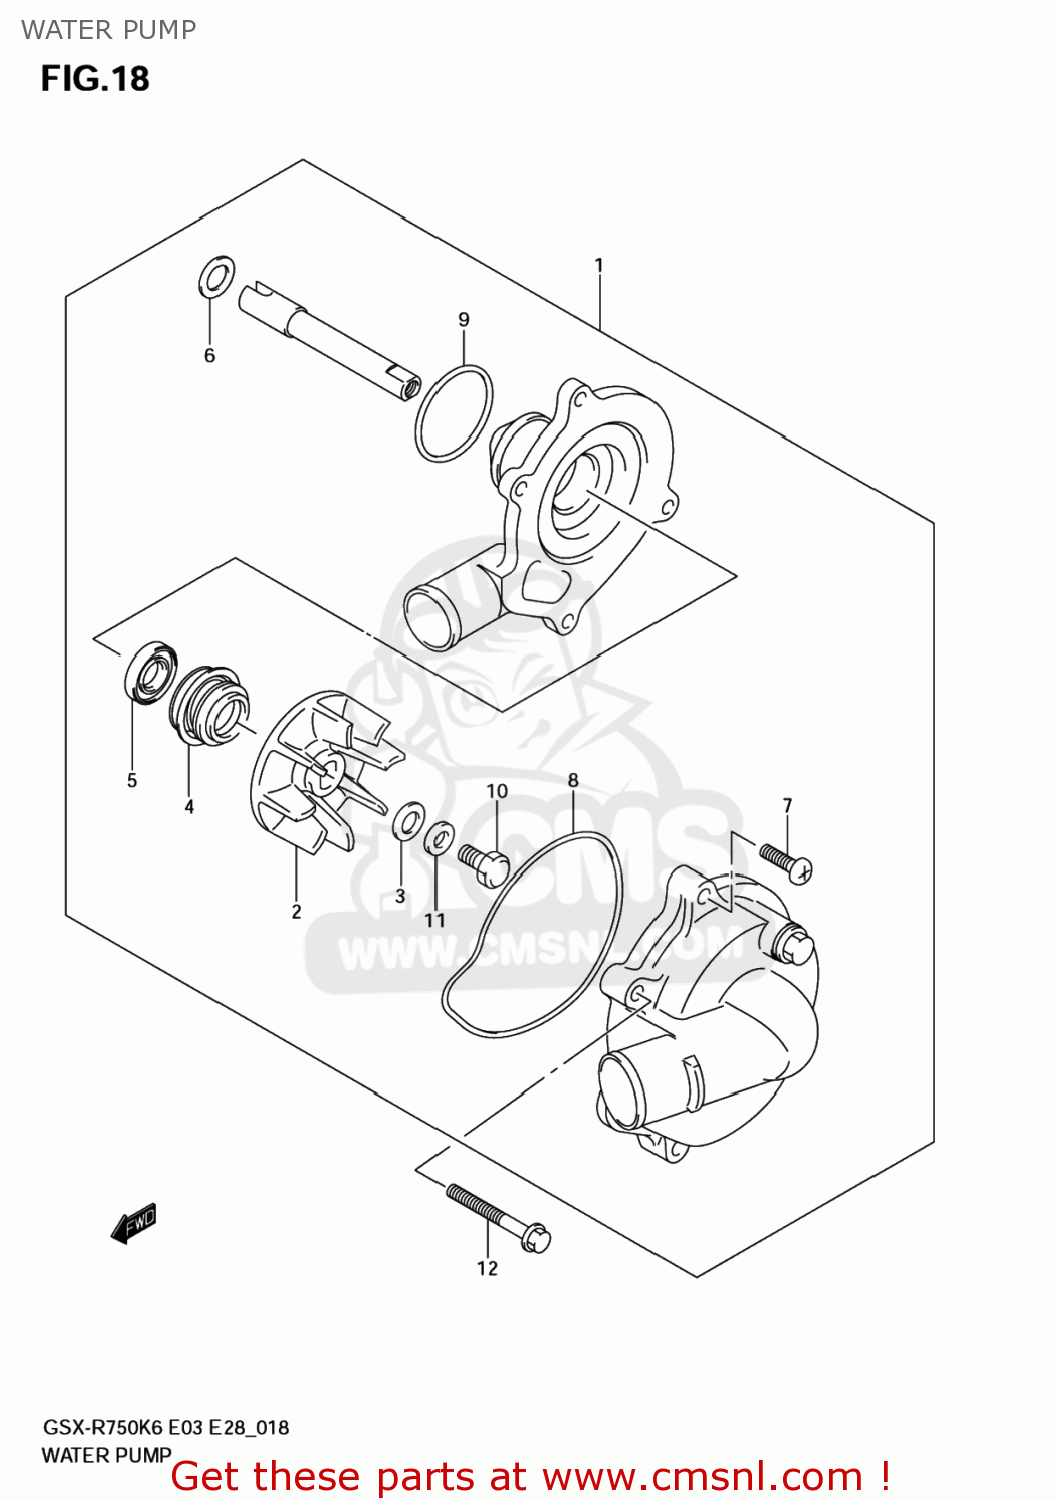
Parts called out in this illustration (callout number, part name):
1	PUMP ASSY,WATE
2	IMPELLER
3	GASKET(6X15X2.2) (NAS)
4	SEAL,MECHANICAL
5	SEAL,OIL
6	SHIM(10X18X1)
7	SCREW 6X16
8	O RING
9	O RING,WATER PUMP HOLDER
10	BOLT(6X13)
11	WASHER
12	BOLT
